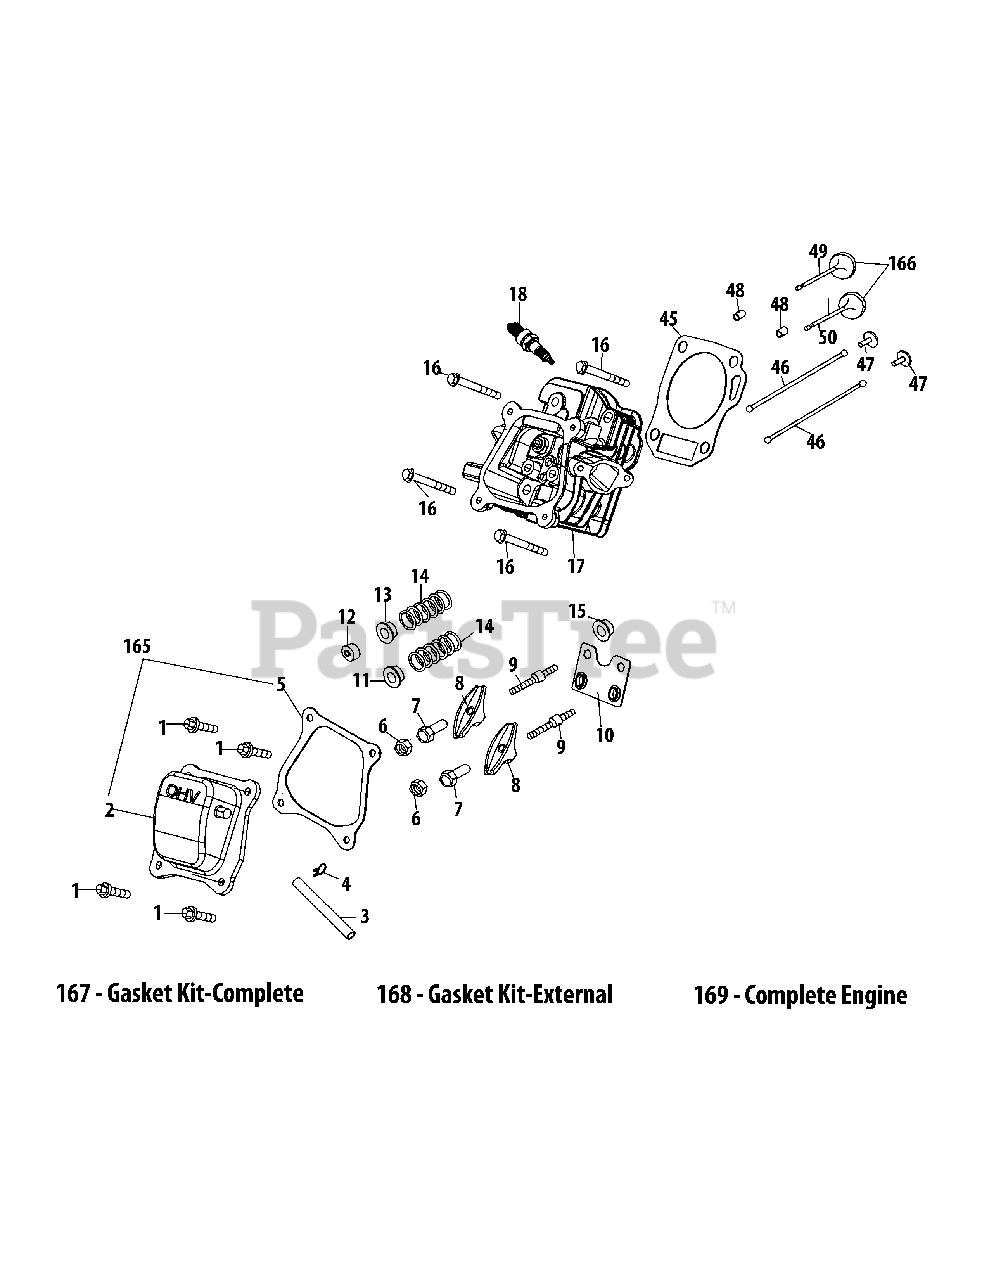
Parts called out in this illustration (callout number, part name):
1	Bolt M6×16
2	Valve Cover
3	Exhaust Piping
4	Breather Hose Clamp
5	Valve Cover Gasket
6	Nut,Pivot Locking
7	Adjusting Nut ,Valve
8	Rocker Arm
9	Bolt,Pivot
10	Push Rod Guide
11	Valve Spring Retainer (Intake)
12	Exhaust Lash Cap
13	Valve Spring Retainer (Exhaust)
14	Valve Spring
15	Valve Seal (Intake)
16	Bolt M8×55
17	Cylinder Head Assembly
18	Spark Plug/F6Rtc
45	Gasket,Cylinder Head
48	Dowel Pin 10×16
49	Exhaust Valve
50	Intake Valve
165	Valve Cover Kit
167	Gasket Kit-Complete
168	Gasket Kit-External
169	Complete Engine
